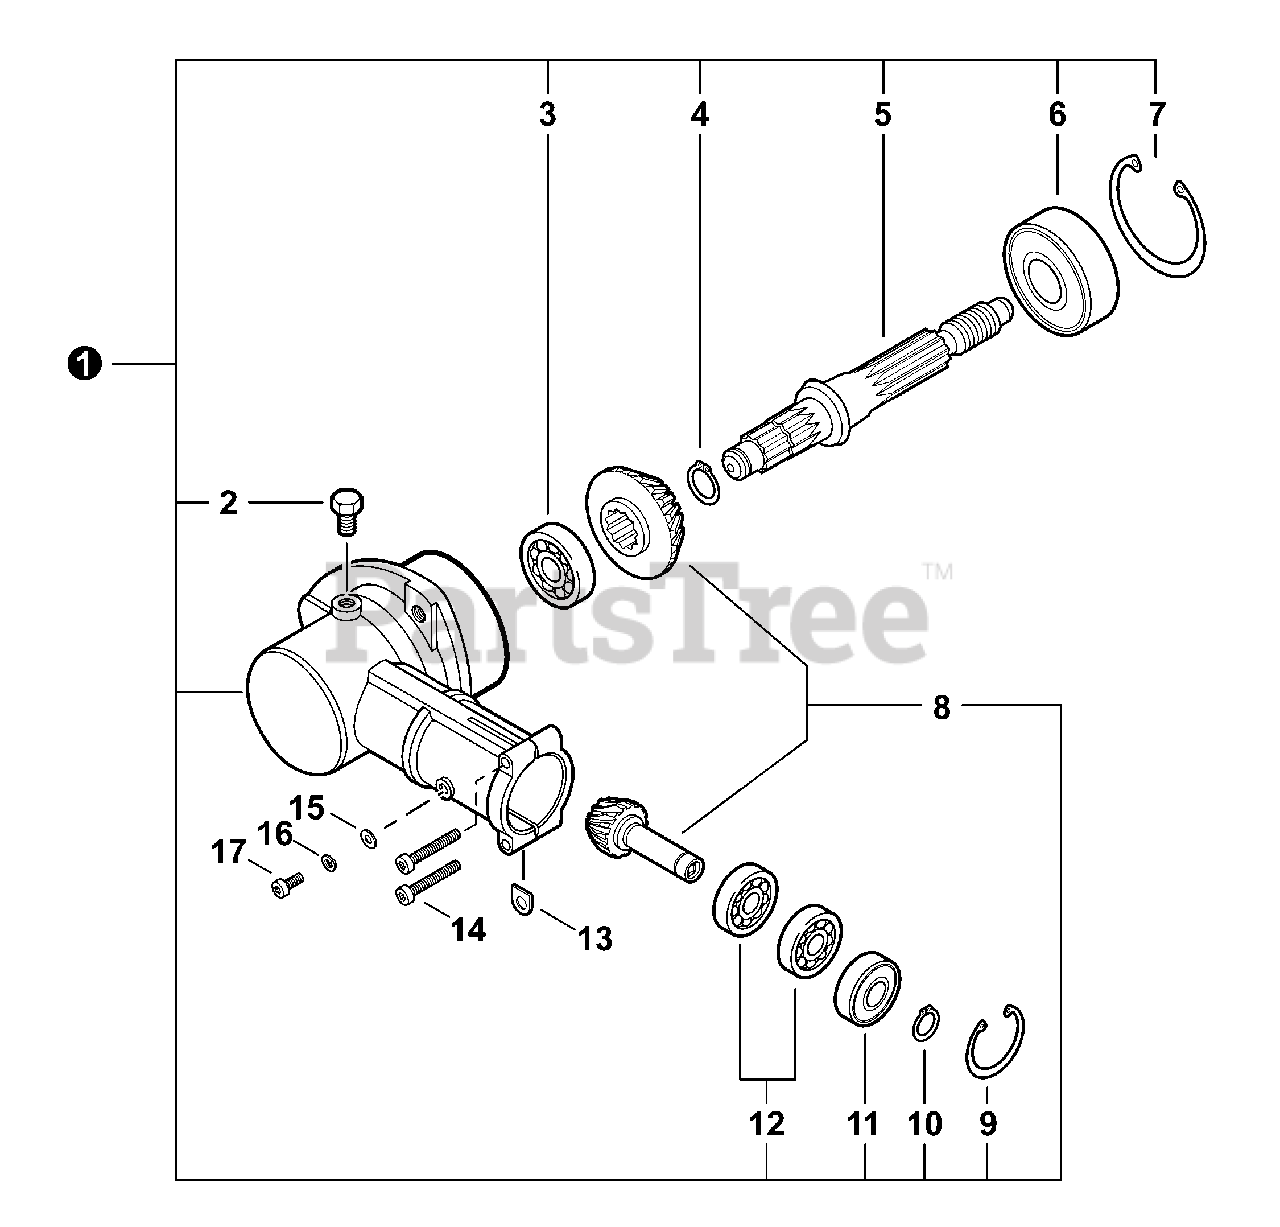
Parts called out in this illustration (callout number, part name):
1	GEAR CASE ASY
2	BOLT - 8×8
3	BEARING, BALL - 629
4	RING, RETAINING - 12
5	GEAR, SHAFT
6	BEARING, BALL - 609
7	RING, RETAINING - 42
8	GEAR SET
9	RING, RETAINING - 22
10	RING, RETAINING - 10
11	BEARING, BALL - 6900Z
12	BEARING, BALL - 6900
13	WASHER, SHIM
14	BOLT, TORX 5×25
15	WASHER, FLAT 5.5×10×0.8
16	WASHER, SPRING 5
17	BOLT, TORX 5×10
